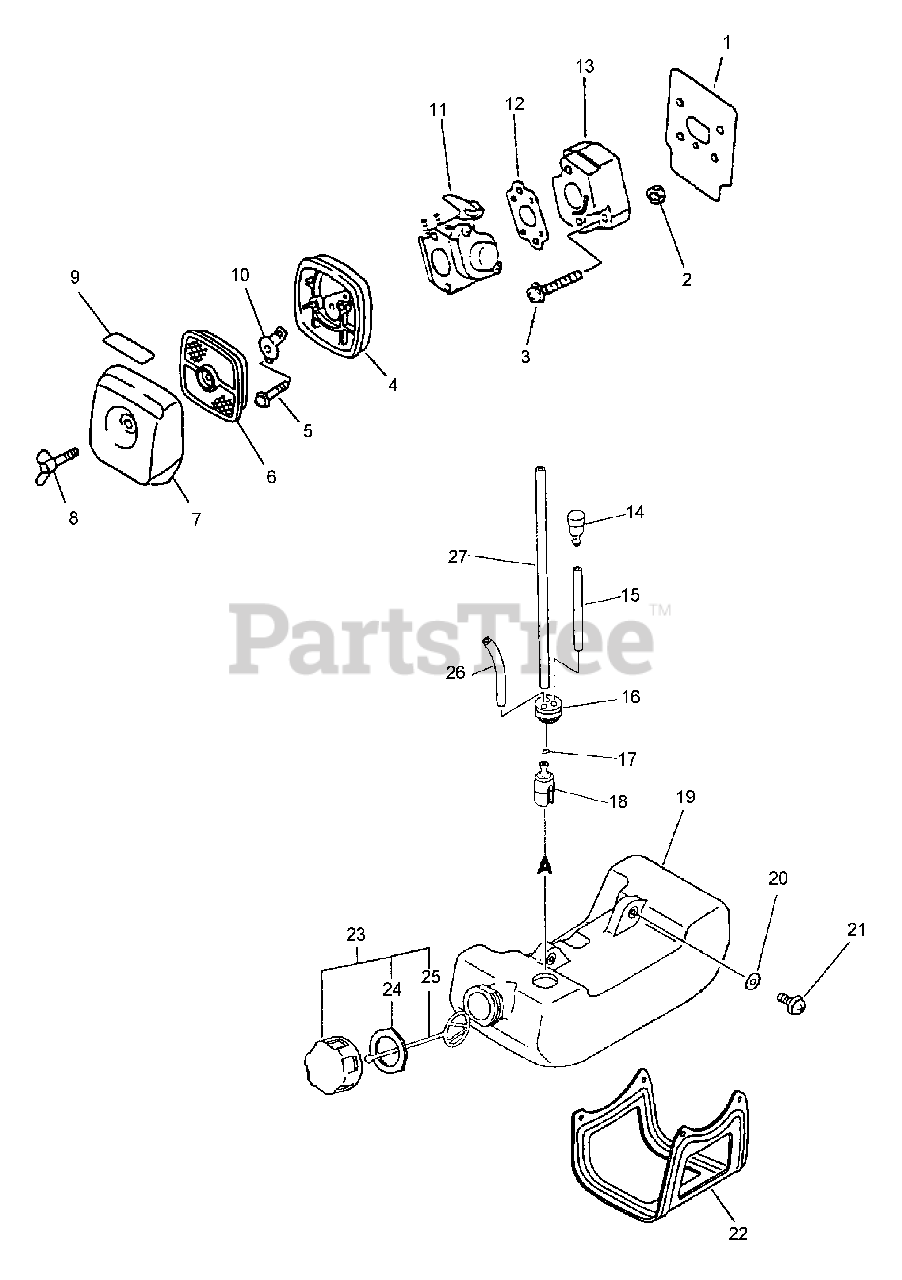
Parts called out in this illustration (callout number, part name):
1	SHIELD, INTAKE
3	SCREW - 5X20
4	CASE, AIR FILTER
5	SCREW - 5X65
6	FILTER, AIR - SINGLE LAYER
7	COVER, AIR FILTER - BLACK
8	THUMBSCREW
9	LABEL - CHOKE
10	PLATE, PREVENT
11	CARBURETOR C1U-K52
12	GASKET, INTAKE
13	INSULATOR, INTAKE
14	VENT, FUEL TANK
15	PIPE - 3X5X70 -- BLACK
16	GROMMET
17	CLIP - 6
18	FILTER, FUEL
19	FUEL TANK ASSY
20	WASHER - 5
21	SCREW - 5X16
22	GUARD, FUEL TANK
23	CAP ASSY
24	GASKET, CAP
25	CONNECTOR, CAP
26	PIPE - 3X6X90 -- CLEAR
27	PIPE - 3X5X180 -- BLACK
